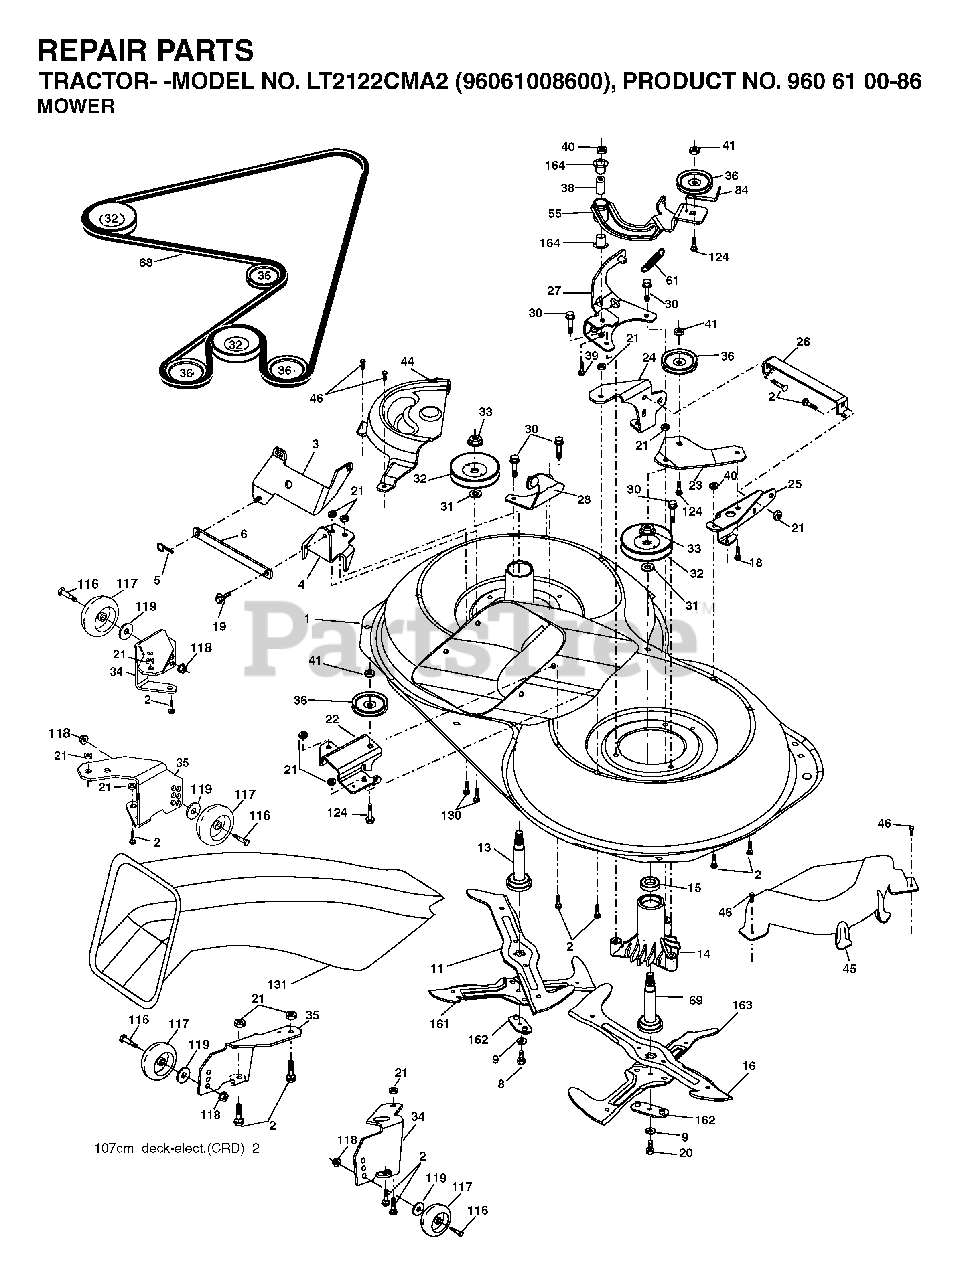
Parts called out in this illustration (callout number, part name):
2	BOLT
3	BRACKET
5	RETAINER-SPRNG RB
6	BAR SWAY
9	LOCKWASHER
11	BLADE.3N1.LH.CRD
13	SHAFT ASM VENT
14	HSG MANDREL
16	BLADE.3N1.RH.CRD
19	BOLT SHD 5/16-18
21	LOCKNUT
22	BRACKET
23	BRACKET
27	BRACKET
30	SCREW, WASHER HEAD
31	WASHER.SPACER.MANDREL
33	NUT.FLANGE.LOCK.TOP
36	PULLEY.IDLER.4.25
40	LOCKNUT
41	NUT LOCK FLG 3/8-16 UNC
45	MANDREL COVER
46	SCREW.1/4-20X5/8
55	ARM IDLER
68	HEX-BELT 107 MOWER
69	SHAFT.ASM.W/LWR.BRG.RH.THREAD
84	KEEPER, BELT IDLER
116	SHOULDER BOLT
117	WHEEL. GUAGE RALLY
118	LOCKNUT
119	WASHER
124	BOLT.3/8-16X1.50
131	CHUTE BAGGER
164	BRNG T
